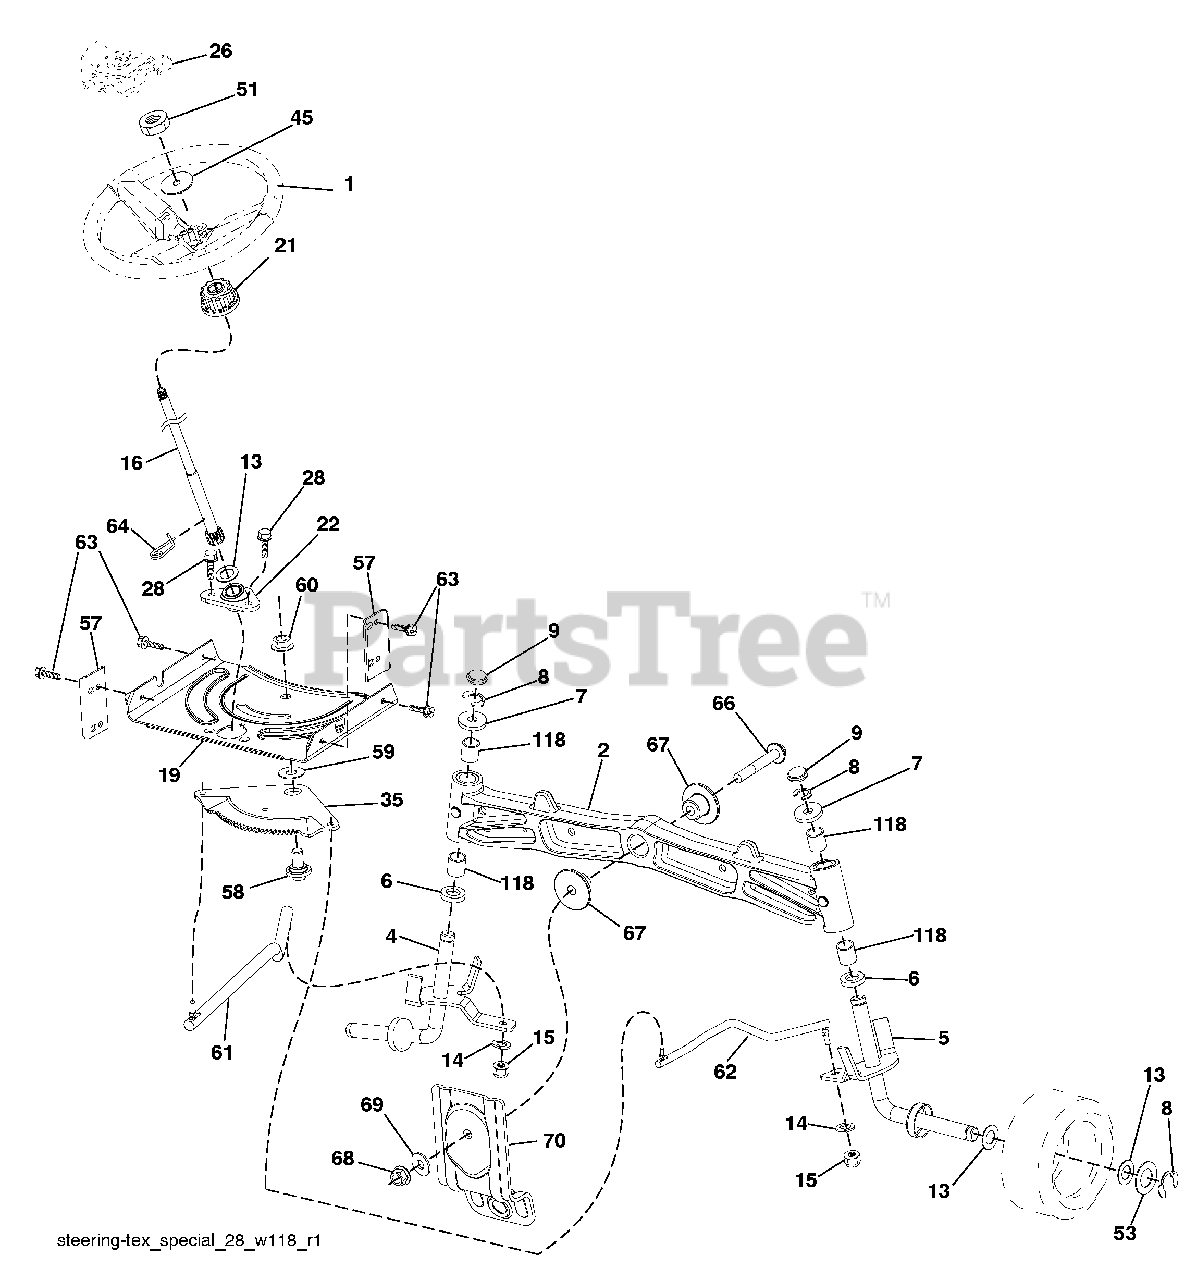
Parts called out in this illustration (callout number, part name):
1	Wheel, Steering
2	Axle Asm., Front
4	Spindle Asm., LH
5	Spindle Asm., RH
6	Bearing, Race Thrust Harden
7	Washer 25/32 x 1-5/8 x 16 Ga.
8	Ring, Klip #T5304-75
9	Cap, Spindle
13	Washer 25/32 x 1-1/4 x 16 Ga.
14	Washer, Lock Hvy Hlcl Spr 3/8
15	Nut, Crown Lock 3/8-24 unf
16	Shaft Steering
19	Plate Steering
21	Adapter, Wheel Steering
22	Steering Supt. Lower
26	Insert, Wheel Steering
28	Screw 3/8-16 x 3/4
35	Gear, Sector Plate
45	Washer 9/16 x 2-3/8 x 12 Ga.
51	Nut Hex Jam Toplock 1/2-20 unf
53	Washer Hardened .793 x 1.637 x .060
57	Bracket Upstop
58	Bolt Shoulder Sector Pivot CFM
59	Washer Thrust Sector Steering
60	Nut Flange Lock 5/8-11
61	Draglink, LH
62	Draglink, RH
63	Screw 5/16-18 x 3/4
64	Retainer Clip Spring Steering
66	Bolt Hex Fghd 7/16-14 x 3 Serr
67	Bushing PM Front Axle
68	Nut Lock Flange 7/16-14 Gr. 5
69	Washer 1.5 x .505 x .118
70	Bracket Deck Susp. Front
